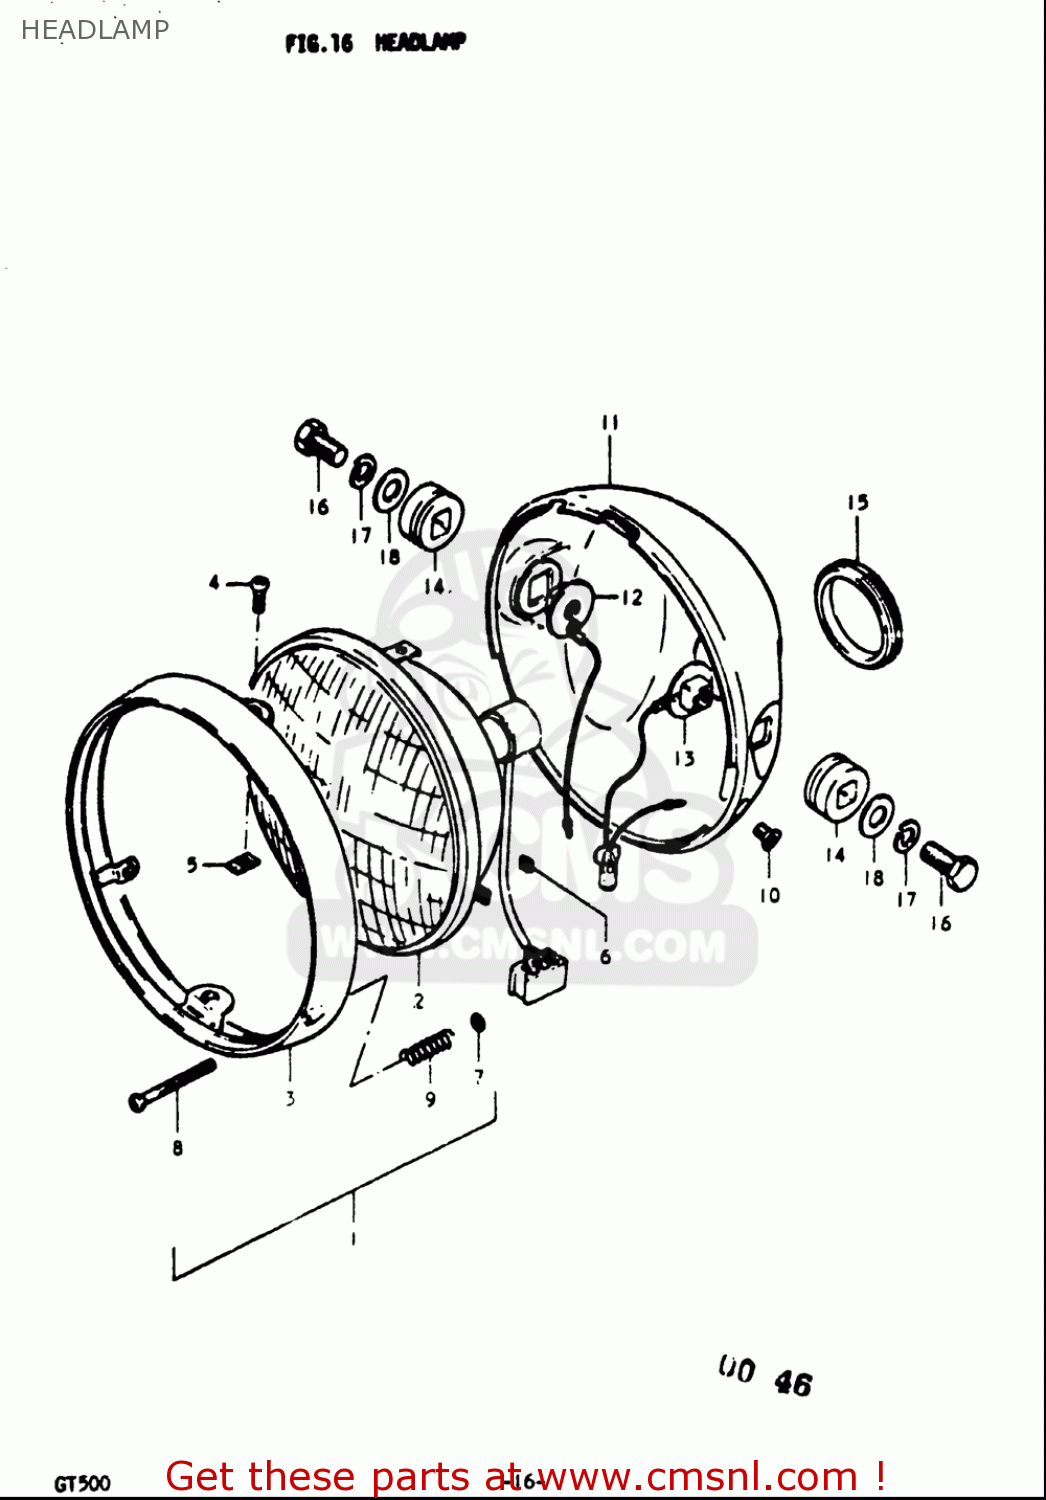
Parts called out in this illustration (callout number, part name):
4	SCREW
5	NUT
6	NUT
7	WASHER
8	SCREW
9	SPRING,HEADLAMP ADJUST
10	SCREW
14	CUSHION,HEADLAMP HOUSING
15	GROMMET,HEADLAMP HOUSING
16	BOLT
17	WASHER,LOCK
18	WASHER
